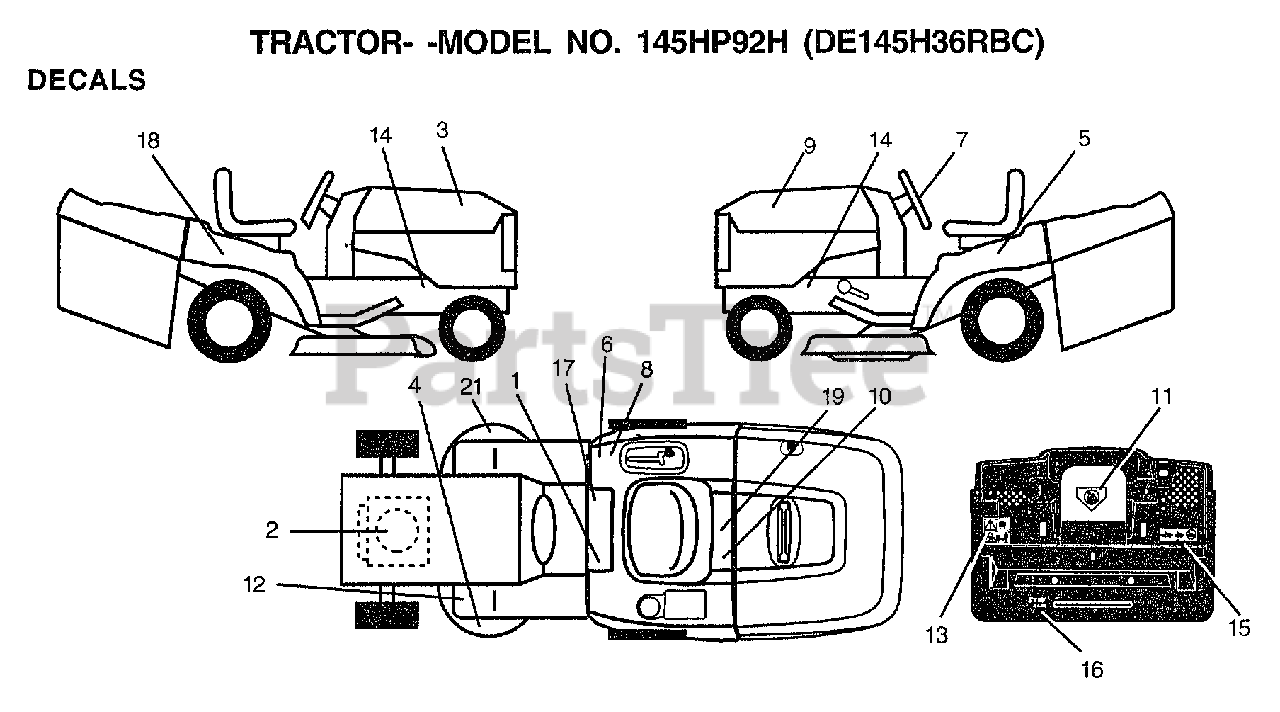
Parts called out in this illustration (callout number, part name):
1	DECAL.READ.O.MANU
2	DECAL, ENGINE
3	DECAL.HOOD.RH
4	DECAL.DECK.MOWER
5	DECAL.FENDER.LOGO
7	DECAL.INST.STEERING
8	DECAL.EURO.ST.CE.
9	DECAL.HOOD.LH
10	DECAL.BATRY.3-3908
11	DECAL.DANGER.CUTF
12	DECAL-BRAKE/CLUTC
13	DECAL.WARNING.BACKPLATE.CRD
14	"DECAL CHASSIS,HOT"
15	DECAL, OPER BAG
16	DECAL.DRAWBAR.LDL
17	DECAL BRAK PARK
18	DECAL.FENDER.LOGO
19	DECAL.BYPASS.FENDER.CRD.LT.YT
21	DECAL.DECK.HEX.BELT
